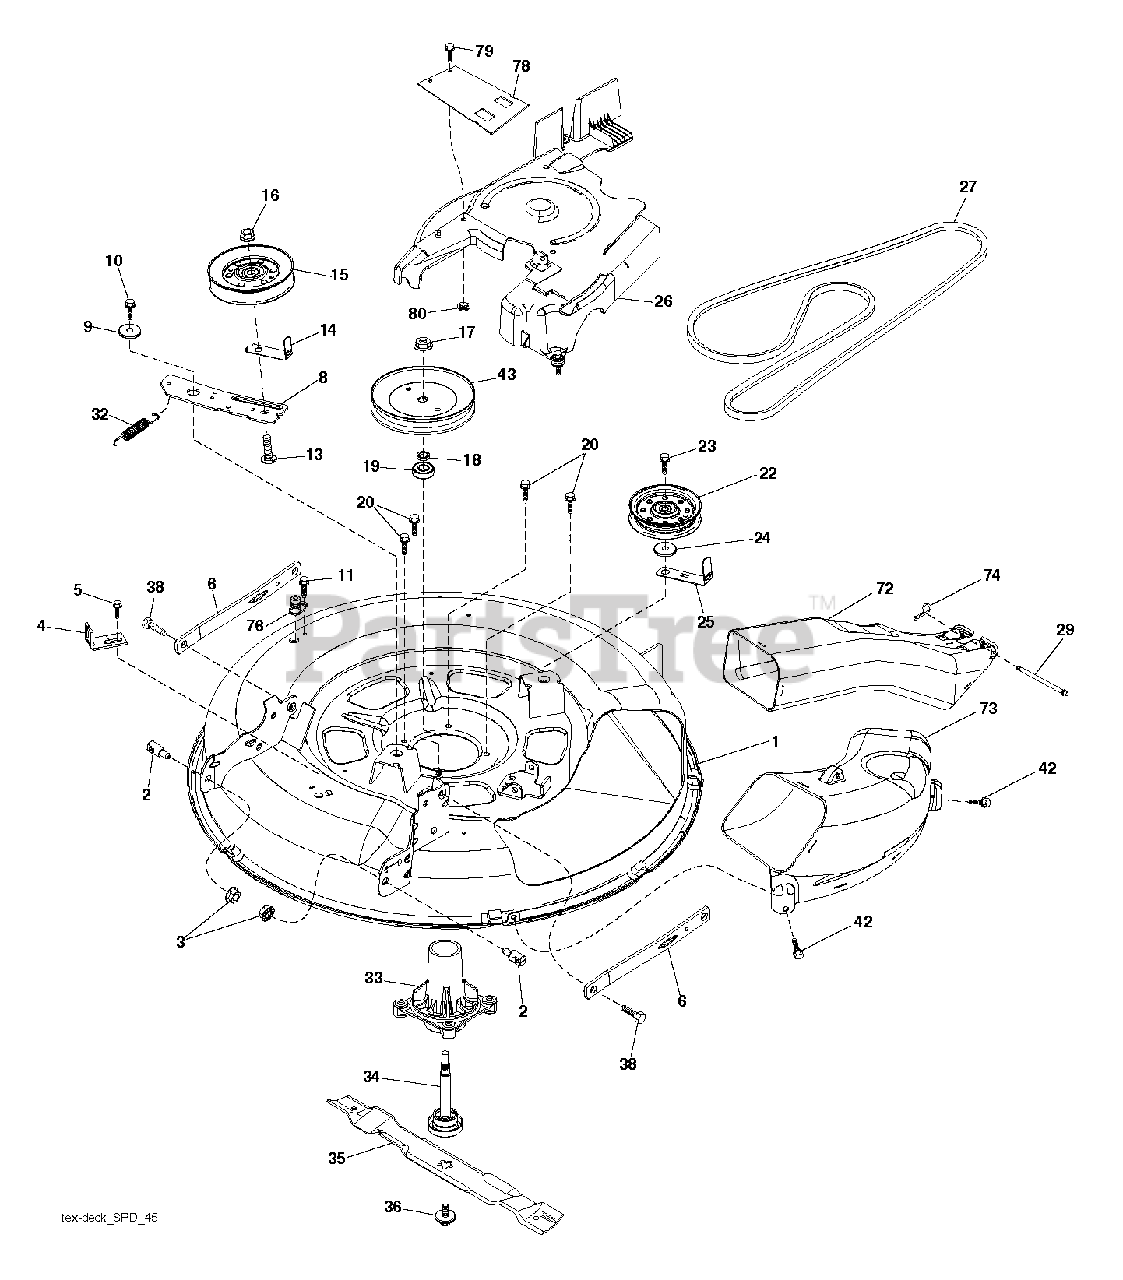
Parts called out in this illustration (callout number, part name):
1	DECK.WELDMENT.PNT.30"SRD
2	STUD.FASTNER.W/ANTI-ROTATE
3	NUT LOCK HEX FLANGE 5/16-18
4	BRACKET.CLUTCH.CABLE
5	BOLT.5/16HEX.WHS.HD
6	ARMS.SUSP.MOWER.REAR.SRD
8	ARM.IDLER.30"SRD
9	SPACER.RETAINER
10	SCREW 3/8-16X1
11	SCREW.1/4-20X5/8
13	BOLT.3/8-16X1.50
14	KEEPER, BELT IDLER
15	PULLEY.IDLER.4.25
16	NUT LOCK FLG 3/8-16 UNC
17	NUT.FLANGE.LOCK.TOP
18	WASHER.SPACER.MANDREL
20	SCREW, WASHER HEAD
22	PULLEY.IDLER.FLAT.46.PR.DR.
23	SCREW LT
24	WASHER
25	KEEPER.BELT.30"SRD
26	COVER.ASM.MANDREL.30"
27	V-BELT.DRIVE.MOWER.30"
29	PIN.HINGE.30".SRD
32	SPRING.MOWER.DRIVE.ELECTRIC
33	HOUSING.MANDREL.4PT.
34	SHAFT.ASM.MDRL.N/GREASE.38
35	BLADE.MOWER.BAGGING.30"
36	BOLT.WASHER.ASM.7/16-2
38	BOLT.SHOULDER
42	SCREW, 3/8-16X3/4
43	PULLEY, MANDREL 6.5 PD
72	CHUTE.UPPER.SRD.30R"
73	CHUTE.LOWER.SRD.30R"
74	Retainer Spring
76	PORT.WASHOUT
78	GUARD ARM CLUTCH
79	SCREW.HI-LO.CONSOLE
80	PALNUT 1/4
